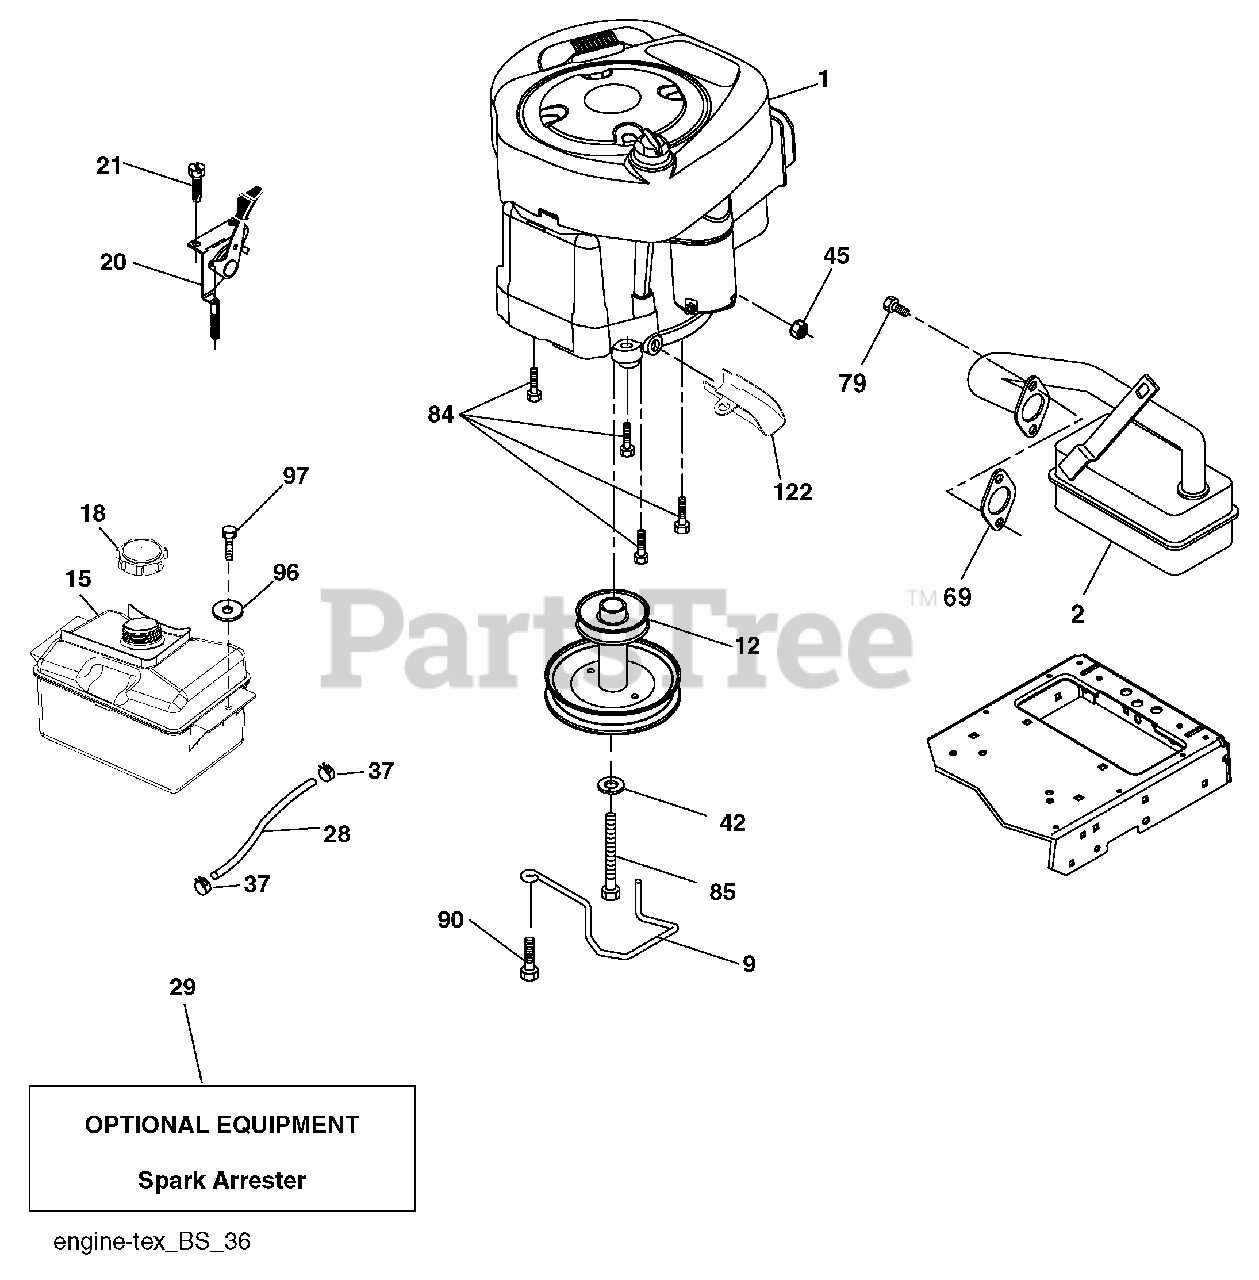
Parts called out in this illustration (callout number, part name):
9	Keeper Belt Engine
12	Pulley Engine
15	Tank Fuel 1.5
18	Cap Fuel
20	Control Throttle
21	Screw #10 x 0.750 BOS Thread
28	Fuel Line
29	Spark Arrester Kit
37	Clamp Hose
42	Washer Lock Hvy HLCL SPR 7/16
45	Nut Keps Hex 1/4-20 unc
69	Gasket
79	Screw Socket HD 5/16 - 18 x 75
84	Screw 3/8-16 x 1-1/4
85	Bolt Hex 7/16-20 x 4 Gr. 5
90	Screw 3/8-16 x 1
96	Washer 9/32 x 7/8 x 16 Ga.
97	Screw 1/4-20 x 3/4
122	Extension Drain Oil
